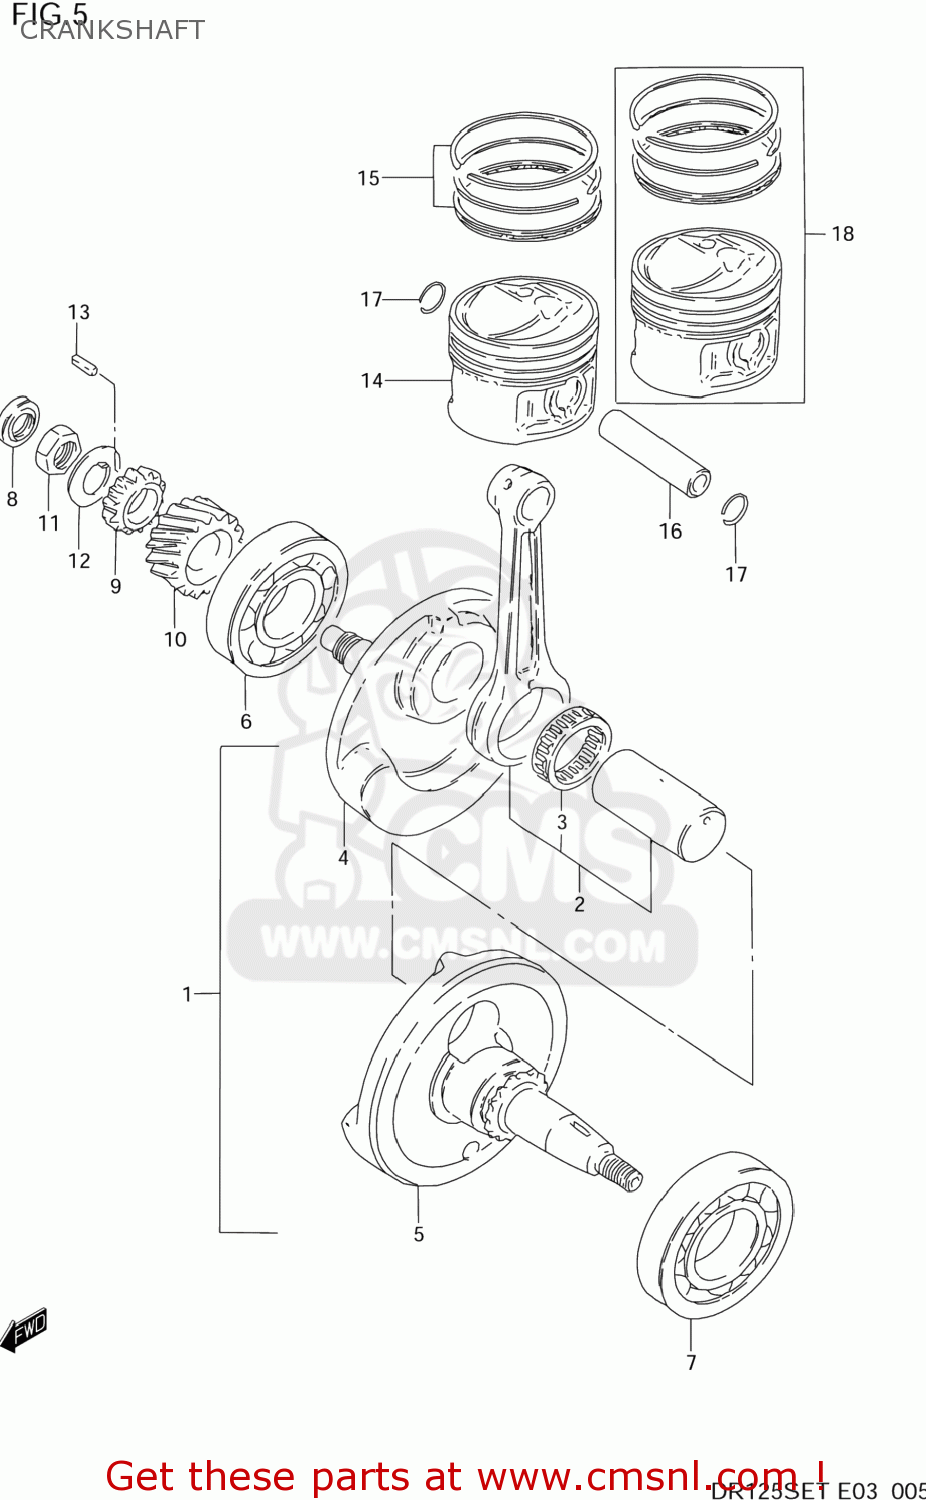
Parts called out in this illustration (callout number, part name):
1	CRANKSHAFT ASSEMBLY
2	CONNECTING ROD SET
3	BEARING(28X36X15.8)
4	CRANKSHAFT,RIGHT
5	CRANKSHAFT,L
6	BEARING(28X68X18)
7	BEARING(35X72X17)
8	SEAL,OIL(12X21X7)
9	GEAR,OIL PUMP DRIVE
10	GEAR,PRIMARY DRIVE
11	NUT
12	WASHER
13	KEY
14	PISTON (STD)
15	RING SET,PISTON
16	PIN,PISTON
17	RING,SNAP 14MM
18	PISTON SET(OS:0.5)
